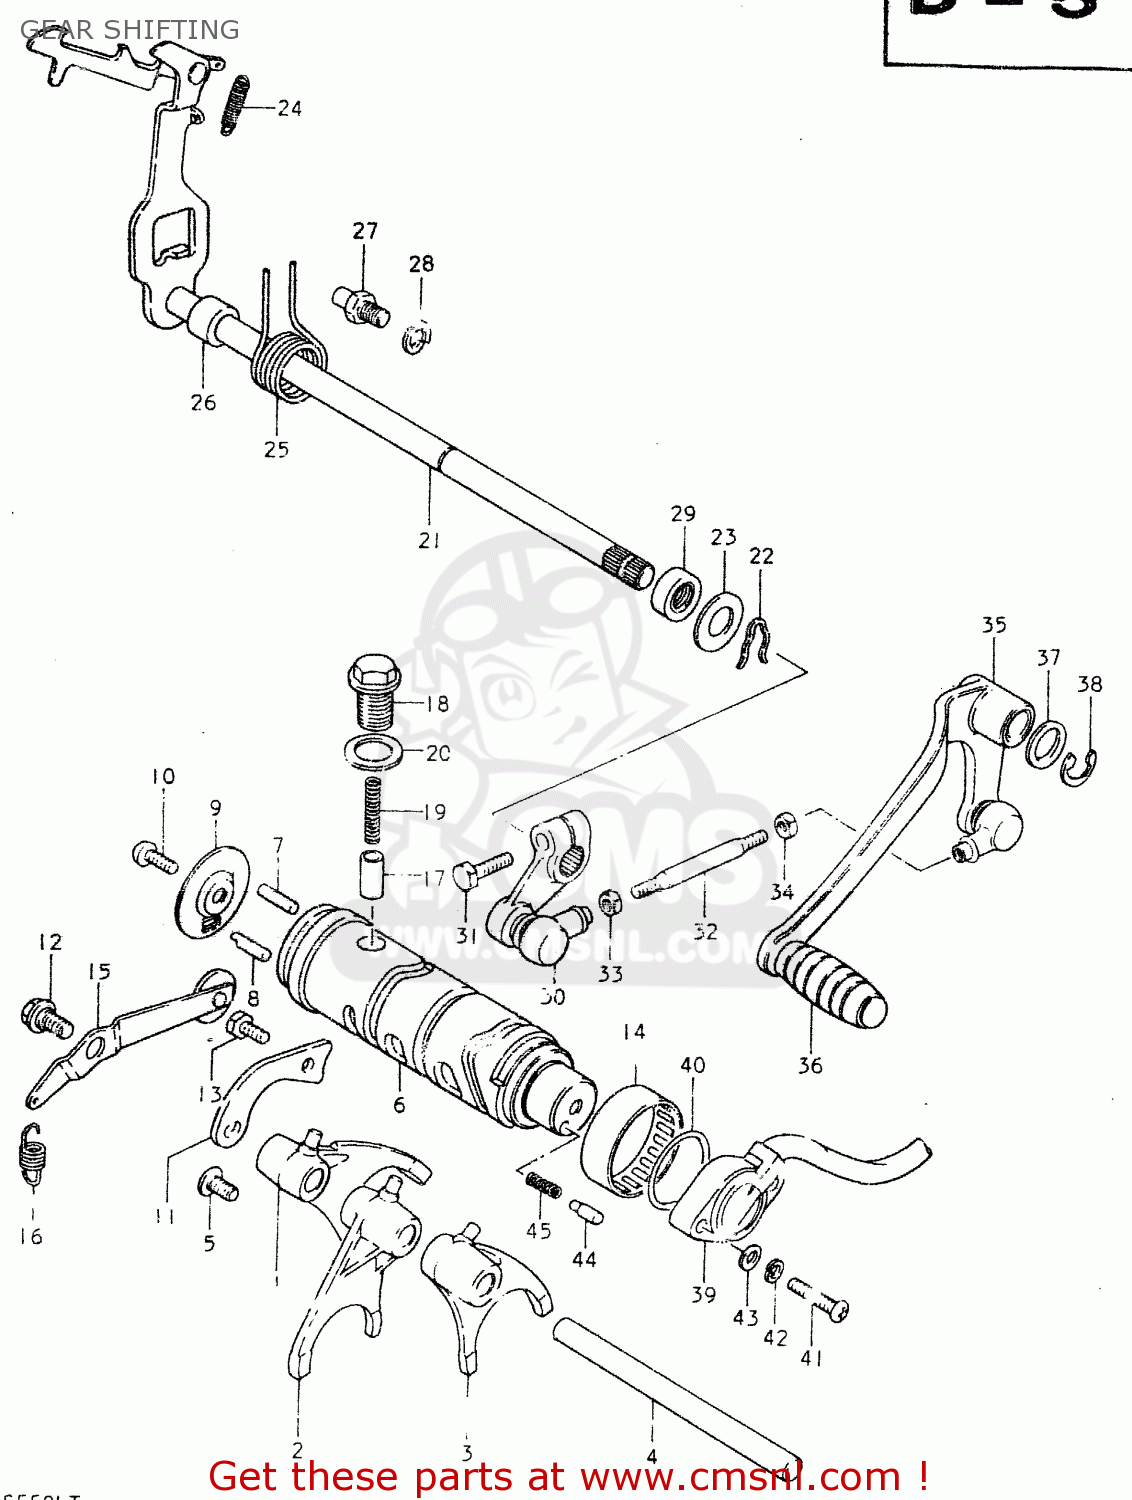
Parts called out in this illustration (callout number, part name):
1	FORK,GEAR SHIFT NO.1
2	FORK,GEAR SHIFT NO.2
3	FORK,GEAR SHIFT NO.2
4	SHAFT,GEAR SHIFT FORK
5	SCREW
6	CAM,GEAR SHIFT
7	PIN(4X18.5)
8	PIN
9	RETAINER,GEAR SHIFT CAM DR PIN
10	SCREW
11	GUIDE,GEAR SHIFTING CABLE
12	BOLT
13	BOLT
14	BEARING(40X47X12)
15	STOPPER,GEAR SHIFT CAM NO.1
16	SPRING
17	STOPPER,GEAR SHIFT CAM NO.2
18	HOLDER,GEAR SHIFT CAM STOP SPR
19	SPRING
20	GASKET(14X19.2X2) (NAS)
21	SHAFT,GEAR SHIFT
22	SPRING,RETAINER
23	WASHER (12.5X27X1.6)
24	SPRING
25	SPRING
26	SPACER(12X20X15.3)
27	STOPPER,GEAR SHIFT CAM
28	WASHER
29	OIL SEAL
30	ARM,GEAR SHIFT LINK
31	BOLT
32	ROD,GEAR SHIFT LINK
33	NUT
34	NUT
35	LEVER ASSEMBLY,GEAR SHIFTING
36	RUBBER,GEAR SHIFT PEDAL
37	WASHER(12.5X20X1)
38	CIRCLIP
39	TERMINAL BASE ASSY,GEAR SHIFT
40	O-RING (D:2.4 ID:26.2)
41	SCREW 5X20
42	LOCK WASHER
43	WASHER
44	PIN(5X15.5)
45	SPRING
